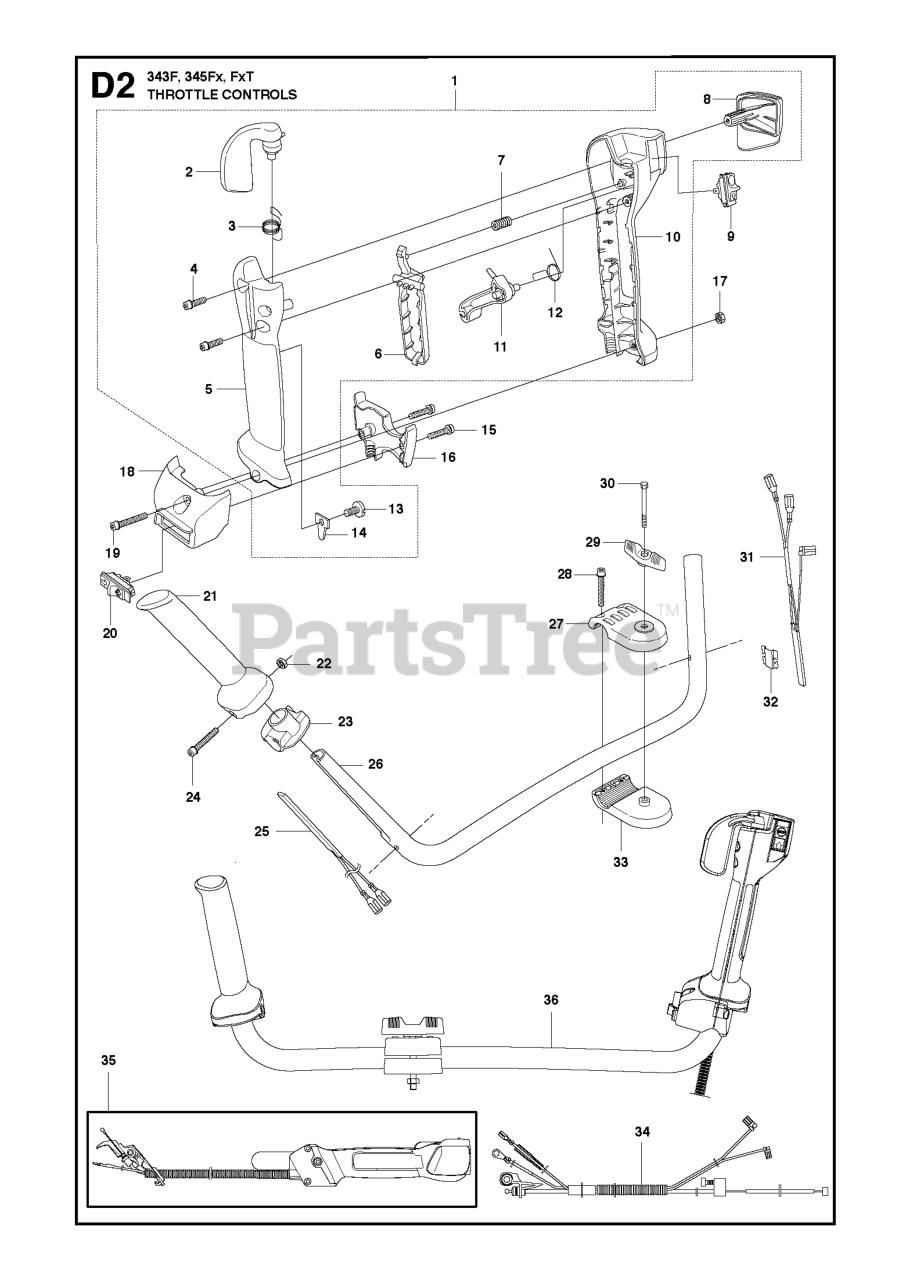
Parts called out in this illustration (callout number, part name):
1	THROTTLE HANDLE
2	THROTTLE TRIGGER
3	RP SPRING
5	HANDLE
6	THROTTLE LOCK
9	STOP BUTTON
10	HANDLE
15	SCREW
16	HOLDER
17	NUT M6M M5
18	HOLDER
19	SCREW
20	SWITCH (G)
22	NUT M6M M5
25	HEATING ELEMENT
26	%HANDLE
26	RP HANDLE
27	HANDLE HOLDER UPPER
30	SCREW 6X70
31	HEATING ELEMENT
32	HOLDER
33	HANDLE HOLDER LOWER
34	WIRING ASSY
35	THROTTLE HANDLE ASSY
36	HANDLEBAR
